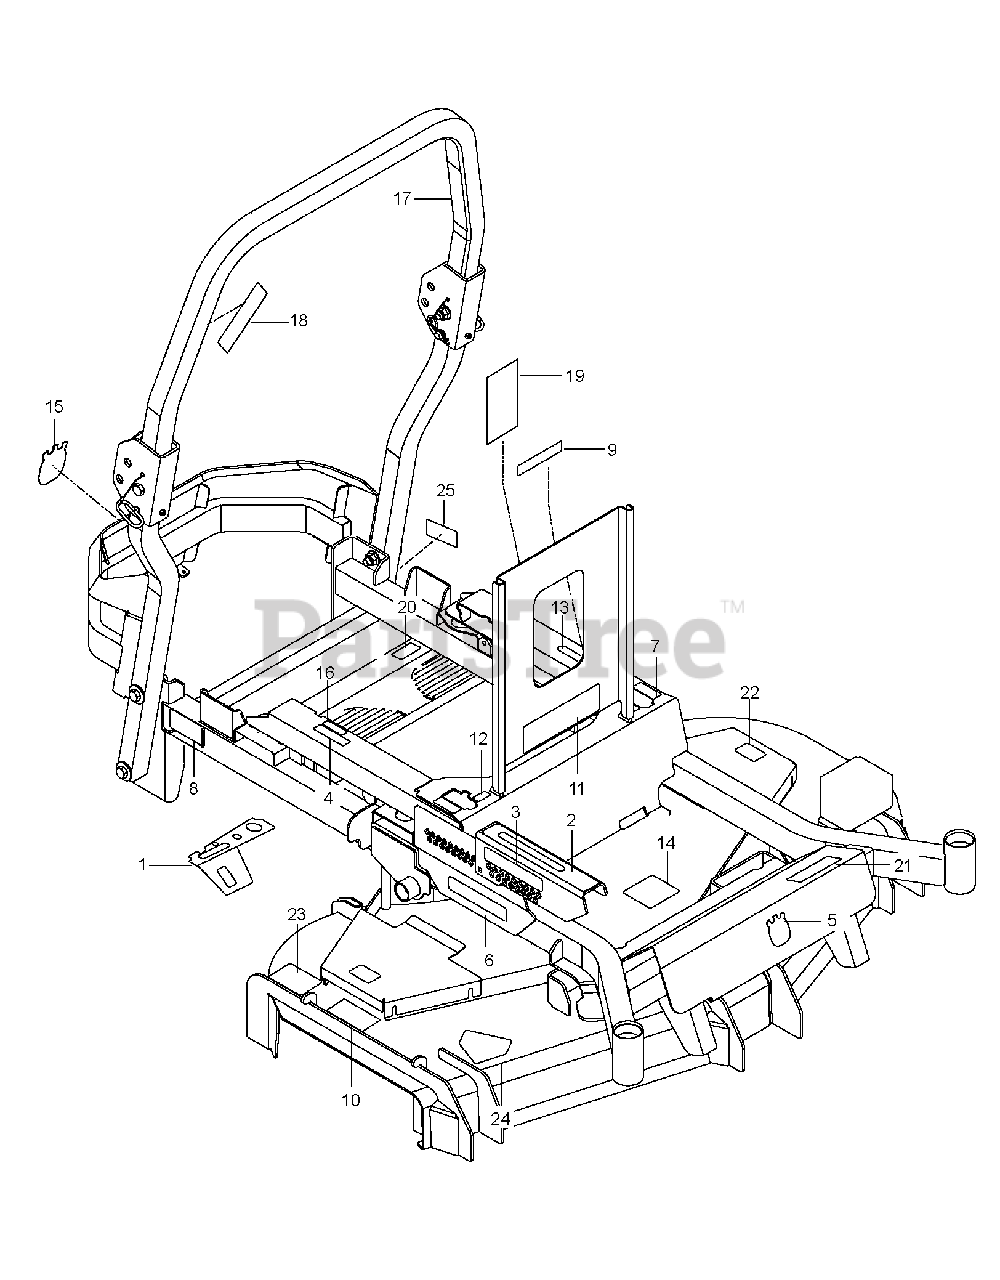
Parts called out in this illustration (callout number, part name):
1	DECAL, CONTROL, GAS
2	DECAL, HEIGHT
3	DECAL, HEIGHT
4	DECAL, WARNING SPARK ARRESTOR
5	DECAL.AUGER.HUSQ.CROWN.SNOW
6	RP.DECAL.BADGE.170MM.TEXTLOGO
7	DECAL.ZTR.MOTCONTRL.SYMBOL.HUS
8	DECAL, BELT DRIVE
9	EURO DECAL-BATTERY WARNIN6
10	DECAL, EURO SEVERING
11	DECAL, WARNING
12	DECAL.STR.S.T.SYSMBOLONLY.2014
13	DECAL.ZTR.PARKBRAK.SYMBOL.2014
14	DECAL, BELT ROUTING
15	DECAL, CROWN H, 110MM
16	DECAL, FUSE
17	DECAL, ROPS, WARNING
18	DECAL, ROPS
19	DECAL, SERVICE
20	DECAL, FUEL
21	DECAL ZTR PZ60
22	DECAL.DECK.6MIL.EURO.NOSTEP
23	DECAL.DECK.6MIL./DEF.SHLD.WARN
24	DECAL, DECK DEFLECTOR, WARNING
25	DECAL, PROP. 65
